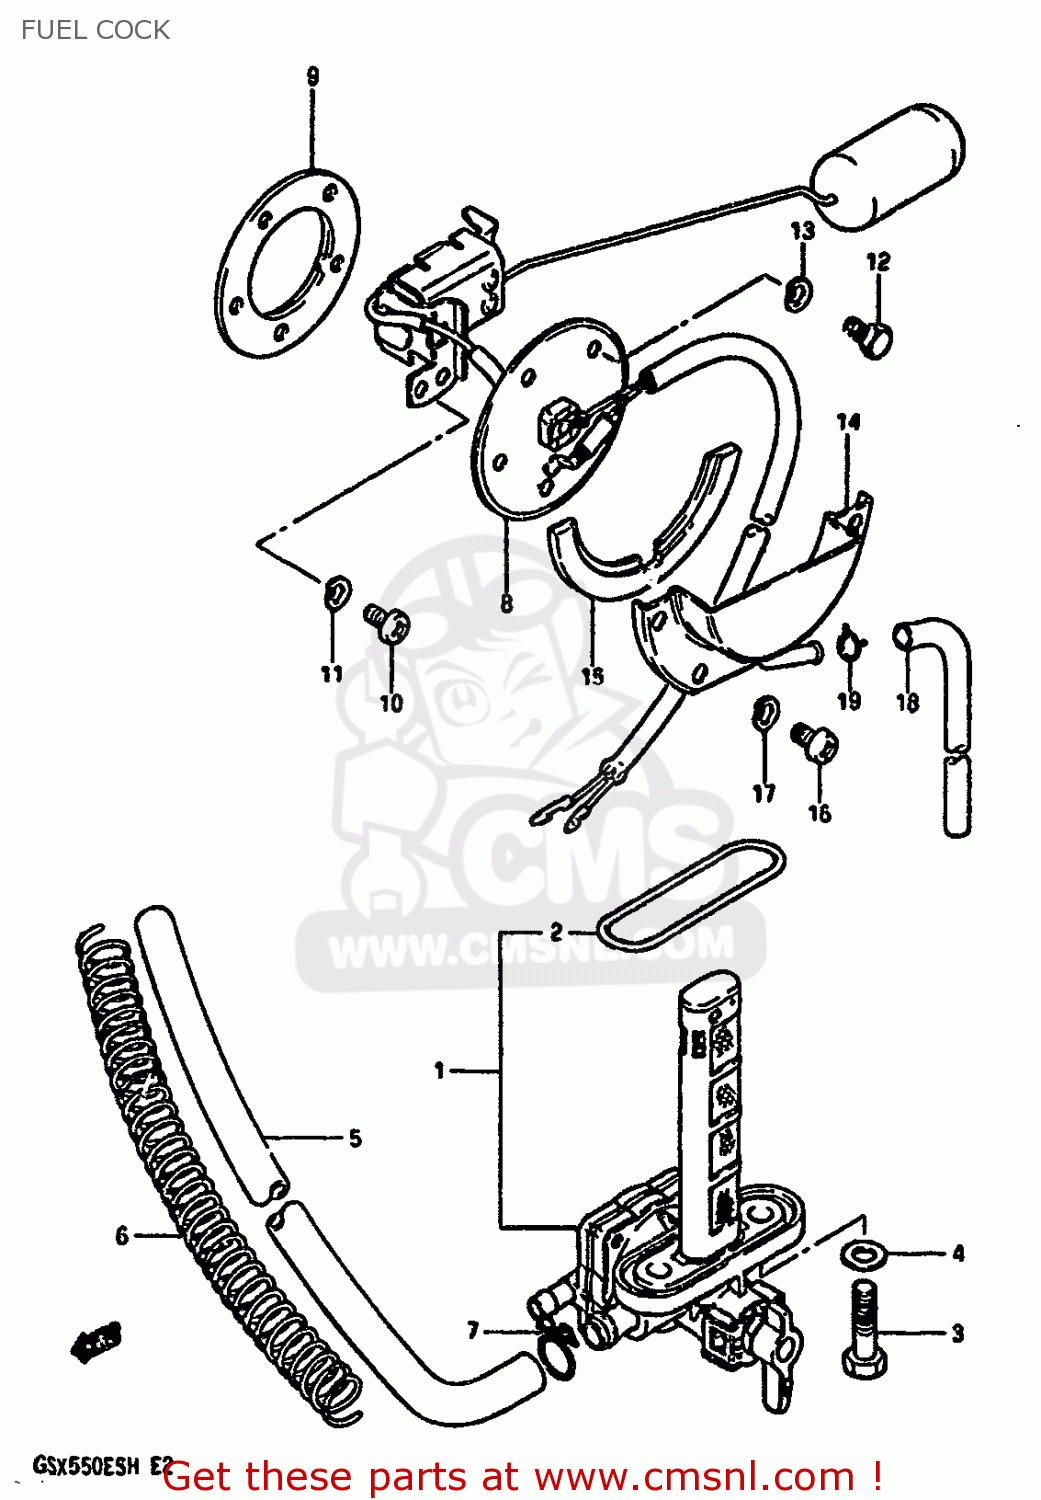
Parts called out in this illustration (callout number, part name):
1	COCK ASSY,FUEL
2	O RING
3	BOLT(6X20)
4	GASKET
5	HOSE
6	SPRING
7	CLIP
8	GAUGE ASSEMBLY,FUEL LEVEL
9	GASKET,FUEL LEVEL GAUGE (NAS)
10	SCREW 5X10
11	LOCK WASHER
12	BOLT
13	LOCK WASHER
14	PLATE,FUEL DRAIN
15	GASKET (NAS)
16	SCREW
17	LOCK WASHER
18	HOSE,FUEL
19	CLIP
